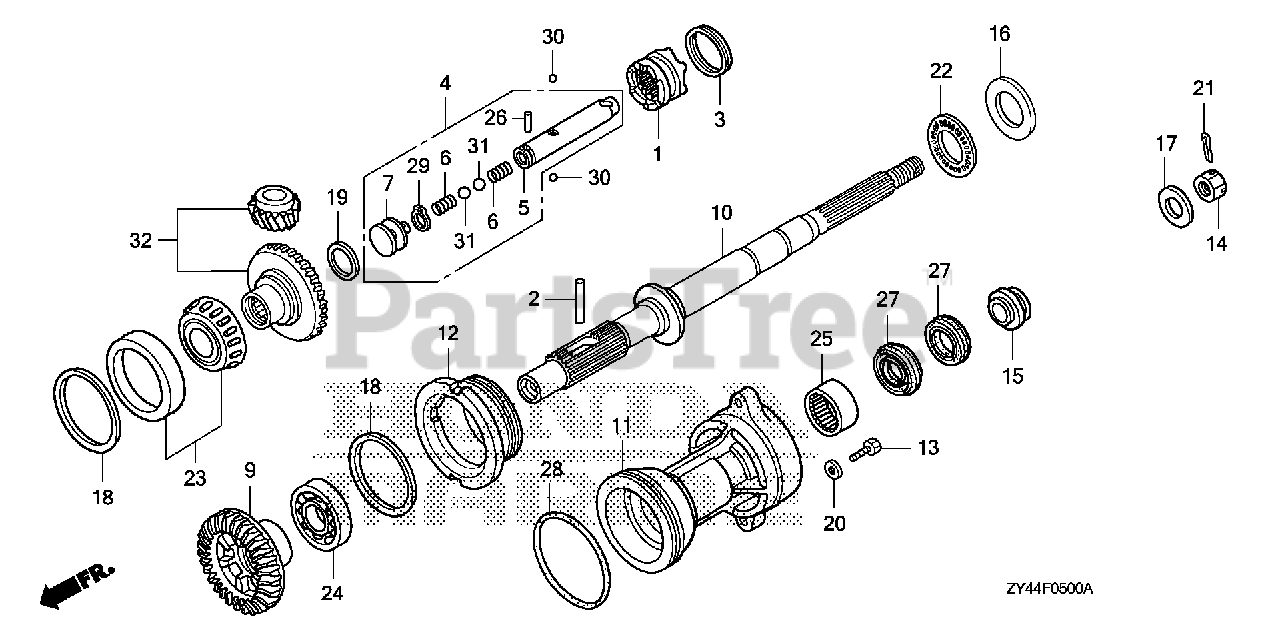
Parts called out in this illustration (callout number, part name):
1	SHIFTER, CLUTCH
2	PIN, SHIFTER (8X50)
3	RING, CROSS PIN
4	SLIDER, SHIFT
5	SLIDER, SHIFT
6	SPRING, SHIFT
7	PLATE, SHIFT
9	GEAR, BEVEL (RVS. 28T)
10	SHAFT, PROPELLER
11	HOLDER, PROPELLER SHAFT *NH282MU* (OYSTER SILVER METALLIC-U)
12	HOLDER, BEARING
13	BOLT, HEX. (12X45)
14	NUT, CASTLE (18MM)
15	WASHER, PROPELLER THRUST
16	WASHER, THRUST BEARING
17	WASHER, PROPELLER
18	SHIM A, BEVEL (0.10)
18	SHIM B, BEVEL (0.15)
18	SHIM C, BEVEL (0.30)
18	SHIM D, BEVEL (0.50)
19	SHIM J, THRUST (2.65)
19	SHIM K, THRUST (2.60)
19	SHIM L, THRUST (2.55)
19	SHIM M, THRUST (2.50)
19	SHIM A, THRUST (2.75)
19	SHIM B, THRUST (2.80)
19	SHIM C, THRUST (2.85)
19	SHIM D, THRUST (2.90)
19	SHIM E, THRUST (2.95)
19	SHIM F, THRUST (3.00)
19	SHIM G, THRUST (3.05)
19	SHIM H, THRUST (3.10)
19	SHIM I, THRUST (2.70)
20	WASHER, PLAIN (12MM)
21	PIN, SPLIT (4.0)
22	BEARING, THRUST (F)
23	BEARING, TAPER (50X90X21.5)
24	BEARING, ANGULAR (50X90X30.2)
25	BEARING, NEEDLE (32X42X30)
26	ROLLER (3X13.8)
27	SEAL, WATER (30X45X7)
28	O-RING (110X3.1)
29	CIRCLIP (OUTER) (15MM)
30	BALL, STEEL (#7) (7/32)
31	BALL, STEEL (#12) (3/8)
